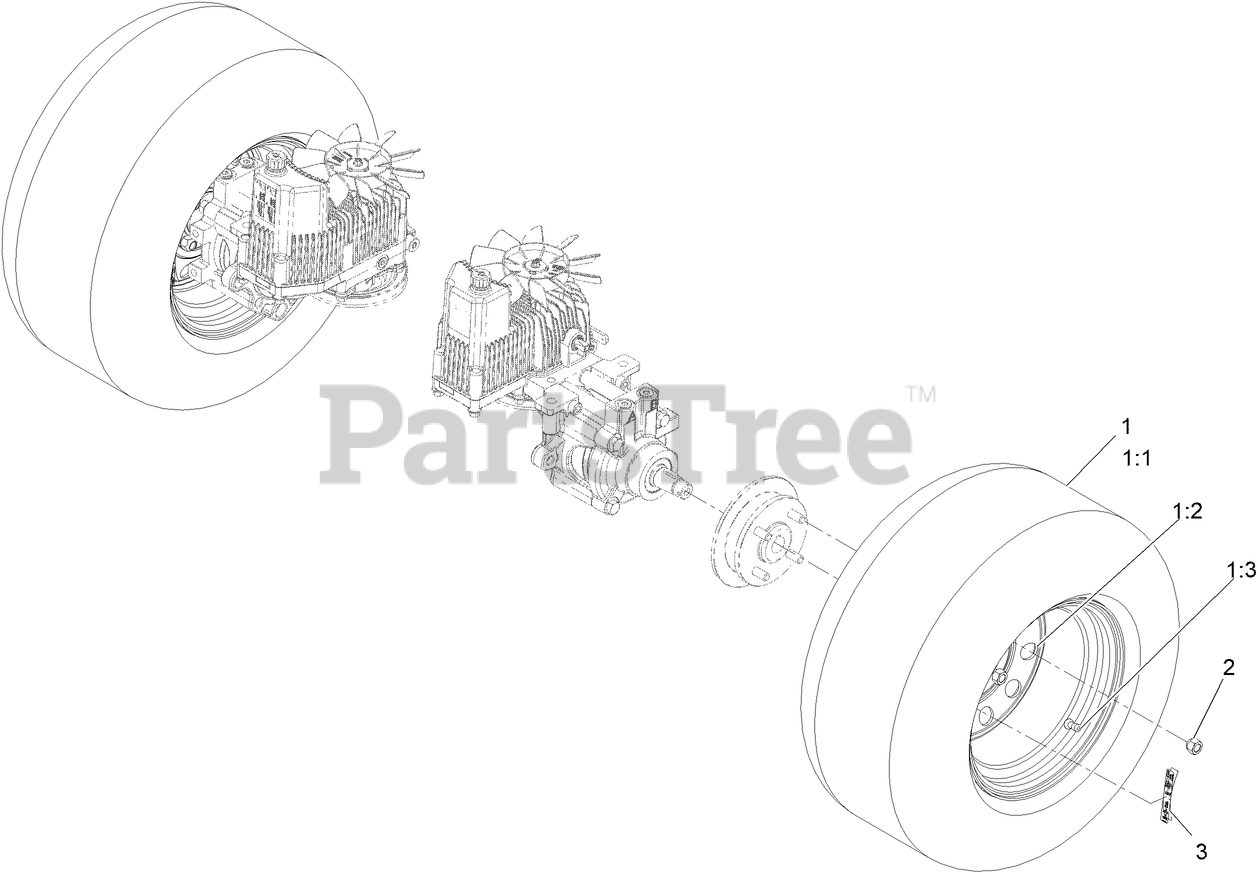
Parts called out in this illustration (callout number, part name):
1	WHEEL AND TIRE ASM
1:1	TIRE-24X12-12
1:2	RIM-GREY
1:3	Stem-Valve
2	NUT-LUG
3	DECAL-TORQUE, WHEEL HUB LUG
